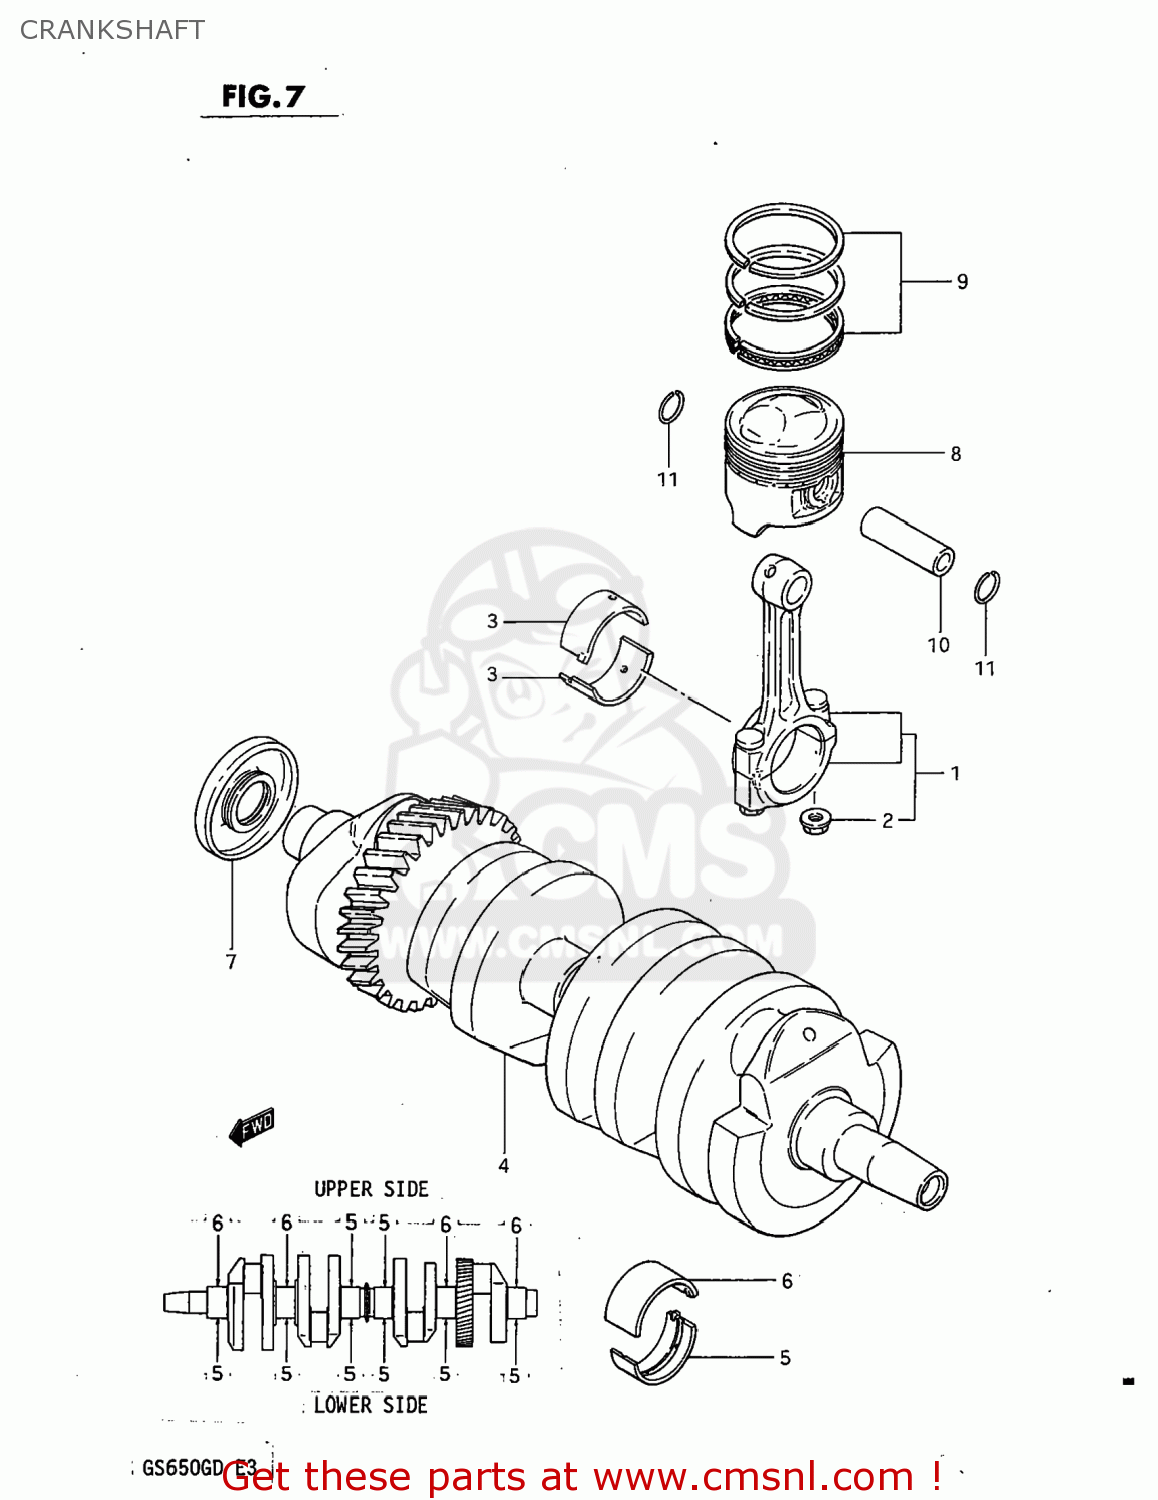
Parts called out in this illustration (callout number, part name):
1	ROD ASSEMBLY,CONNECTING
2	NUT
3	BEARING,CRANK PIN
4	CRANKSHAFT ASSEMBLY
5	METAL CRANKSHAFT
6	METAL CRANKSHAFT
7	OIL SEAL
8	PISTON
9	RING SET,PISTON
10	PIN,PISTON
11	CIRCLIP
